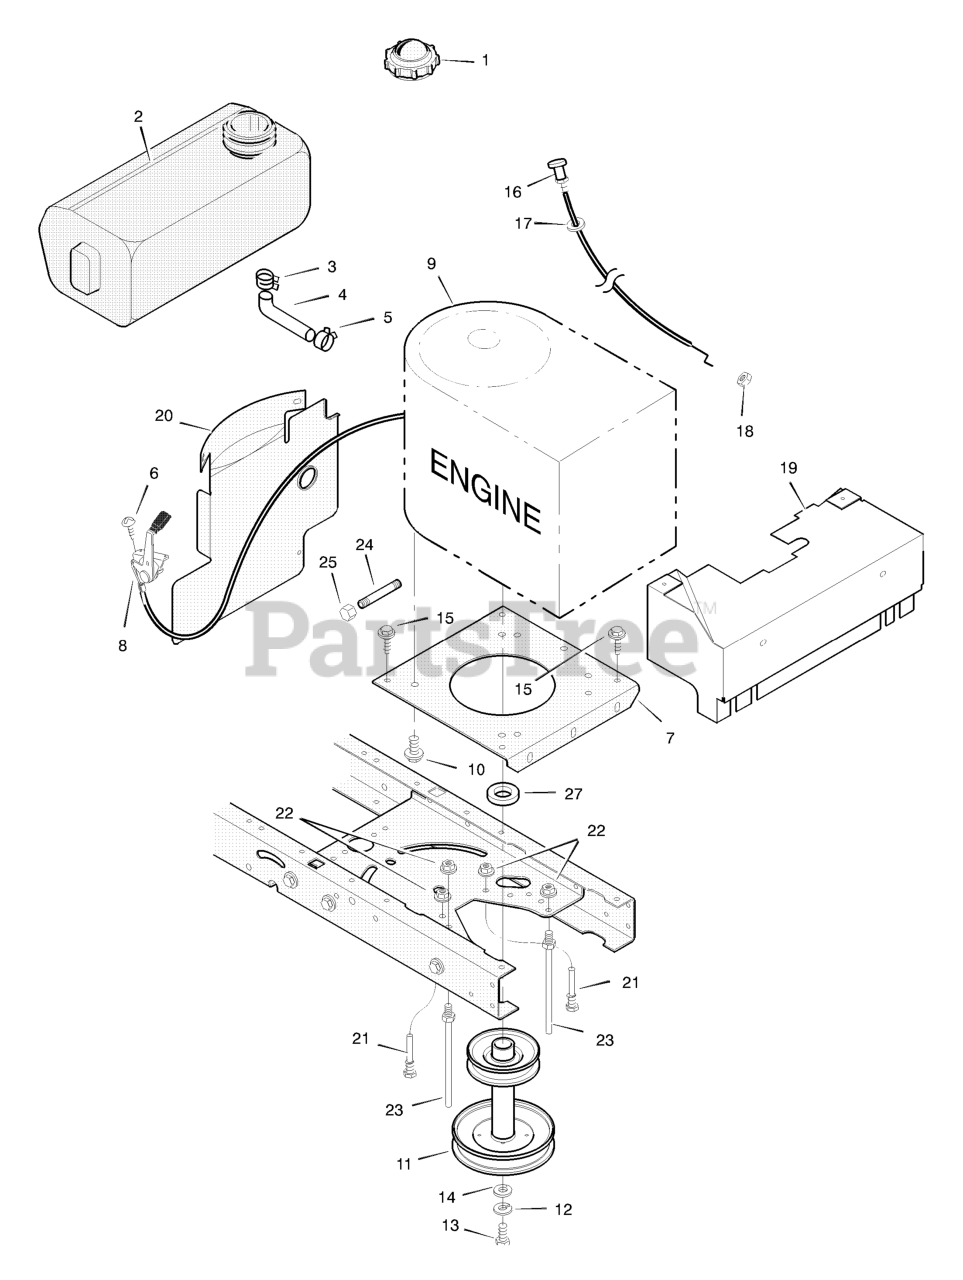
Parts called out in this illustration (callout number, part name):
1	Fuel Cap
2	Fuel Tank
3	Hose Clamp
4	Fuel Line
5	Hose Clamp
7	Plate, Engine
8	Throttle Control
9	Engine *
10	Bolt, Engine Mount
11	Stack Pulley Assembly
12	Lockwasher
13	Bolt, Hex
17	Washer
19	Baffle, Front Engine
20	Baffle, Rear Engine
21	Guide, Belt
22	Nut, Flange
23	Guide, Belt
24	Pipe, Oil Drain
25	Cap, Oil Drain
